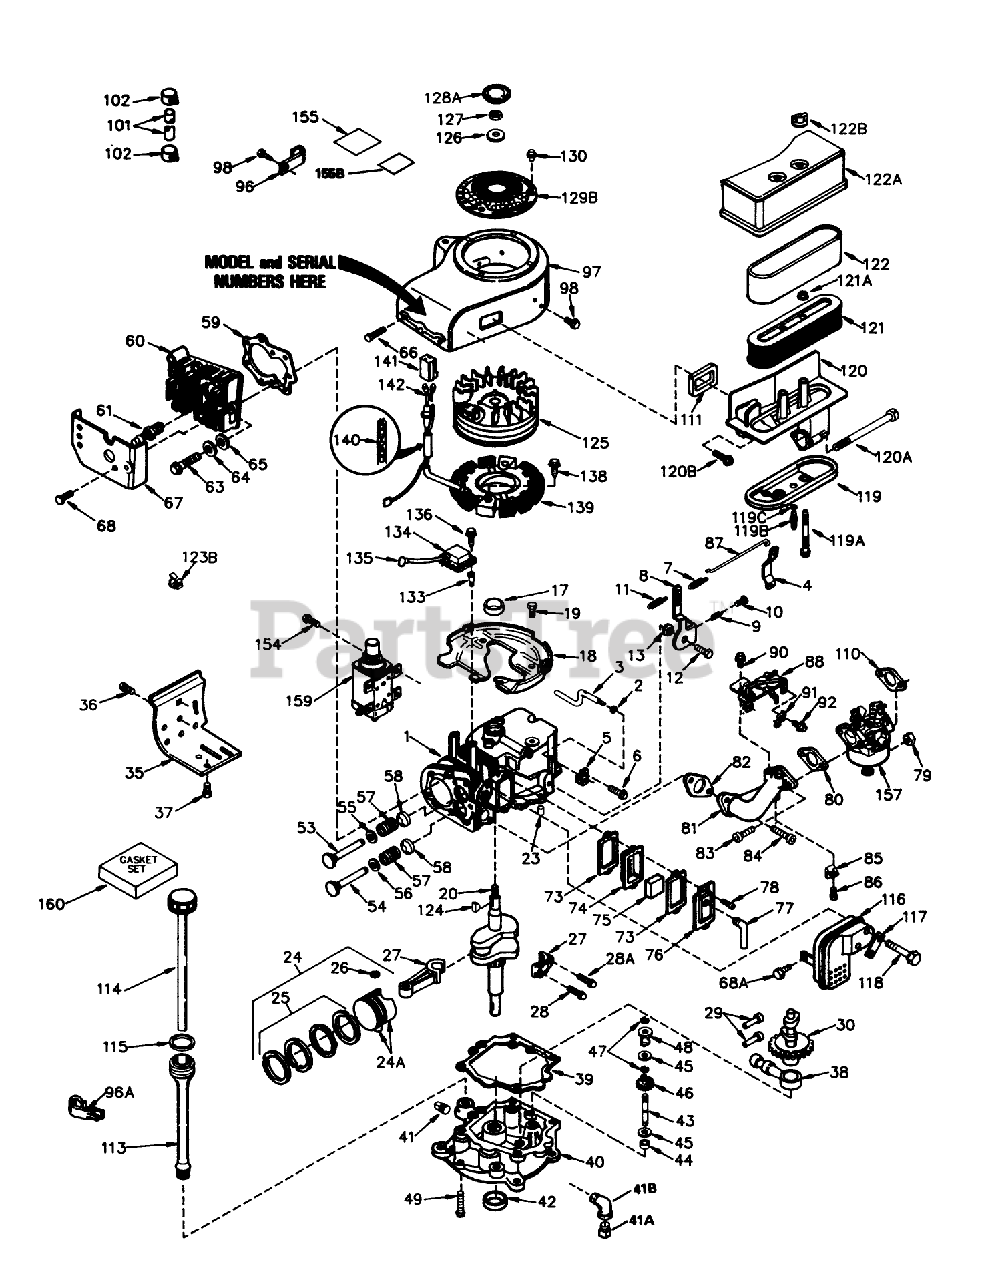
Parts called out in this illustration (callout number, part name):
1	2006A77 WIZARD ROTA
2	Washer-Flat
3	Rod, Governor
4	Governor Lever
5	Clamp-Lever, Governor
6	Screw
7	Spring, Extension
8	Lever, Control (Incl. Ref. #11, 12, 13 110)
9	61709/GIL1515A/95-5
10	Screw
11	Spring, Control
12	SCREW, HEX WASHER HD.
13	Bell crank
17	Seal-Oil
18	Baffle-Blower Housing
19	Screw (1/4-20x19/32)
20	Crankshaft
23	Pin-Dowel
24	Piston, Pin Ring Assy.(Std.) (Incl. Ref. #24A, 25 26)
24	Piston, Pin Ring Assy. (.010 oversize) (Incl. Ref. #24A, 25 26)
24	Piston, Pin Ring Assy. (.020 oversize) (Incl. Ref. #24A, 25 26)
24A	Piston Pin Assy. (Std.) (Incl. Ref. #26)
24A	Piston Pin Assy. (.010 oversize) (Incl. Ref. #26)
24A	Piston Pin Assy. (.020 oversize) (Incl. Ref. #26)
25	Ring Set (Std.)
25	Ring Set (.010" OS)
25	Ring Set (.020" OS)
27	Rod Assy., Connecting (Incl. Ref. #28 28A)
28	Bolt-Rod
28A	Bolt-Rod
29	Lifter-Valve
30	Camshaft (Mechanical Compression Release)
35	Extension-Housing, Blower
36	Screw
37	Screw
38	Pump, Oil
39	Cylinder Cover Gasket
40	Flange Assy., Mounting (Incl. Ref.#41, 41A, 42, 43 45)
41	Plug, Drain
41A	Plug, Oil drain
41B	Elbow, 90 Degrees (Can be purchased locally)
42	Seal-Oil
43	Shaft, Governor
44	Spacer Assy. Governor (Incl. Ref. #41)
45	Washer
46	Gear Assy., Governor (Incl. Ref. #45)
47	Ring-Retaining
48	Spool-Governor
49	Screw (1/4-20x1-3/16)
53	Valve, Exhaust (Standard)(Incl. No. 9)
53	Valve, Exhaust (1/32" oversize)(Incl. No. 9)
54	Valve, Intake (Std.) (Incl. Ref. #58)
54	Valve, Intake (1/32" oversize) (Incl. Ref. #58)
55	Cap-Spring, Valve
56	Seal-Intake Valve
57	Spring-Valve
58	Keeper-Spring, Valve
59	Gasket-Cylinder Head
60	Head Cylinder
61	Plug, Spark (Champion RCJ-8)
63	Screw (5/16-18 X 2)
64	Washer-Belleville
65	Washer-Flat
66	Screw (5/16-18x3/4)
67	Cover-Cylinder Head
68	Screw (1/4-20 X 5/8)
68A	Screw (1/2-20x5/8)
73	Gasket-Cover, Valve
74	Body-Breather
75	Element-Breather
76	Cover-Valve
77	Tube-Breather
78	Screw
79	Nut and Lock Washer (1/4-28)
80	Gasket-Carburetor To Intake Pipe
81	Pipe, Intake
82	Gasket-Pipe, Intake
83	Screw (1/4-28x1)
84	Screw (T-30, 5/16-18x1-3/32)
85	Bracket, Intake Pipe
86	Screw (1/4-20 X 5/8)
87	Link, Throttle
88	Bracket Assy., Control
90	Screw (10-24 x 9/16)
91	Conduit
92	Screw (10-32 x 3/8)
96	Clip Oil Tube
96A	Clip, Oil fill tube
97	Housing, Blower
98	Screw
101	Line-Fuel
102	Clamp-Line, Fuel
110	Clutch Arm Assembly
111	Gasket, Blower Housing
113	Tube-Fill, Oil
114	Dipstick, Oil
115	O-Ring
116	Muffler Assy.
117	62513 SNWTHWR W/284
118	Screw, Hex Hd.
119	Plate, Support
119A	Screw, Truss Hd.
119B	Fitting, Breather Tube
119C	0 Ring
120	Body, Air Cleaner
120A	Screw, Fil. Hd.
120B	Screw, Hex Washer Hd. Self-drill, Self-tap
121	Element, Air Cleaner (Incl. Ref. #121A)
121A	Nut Lockwasher
122	Filter, Poly Pre-cleaner
122A	Cover, Air Cleaner
122B	Nut, Wing
123B	51004 GIL ROTARY TI
124	Key-Flywheel
125	Flywheel ASM
126	Washer-Belleville
127	Nut-Flywheel
128A	Plug, Screen
129B	Screen, Starter
130	Pop Rivet (Can be purchased locally)
134	Solid State ASM
135	Cover-Spark Plug
136	Screw
138	Screw (1/4-20 x 3/4)
139	Coil Assy., Alternator (3 Amp D.C.) (Incl. Ref. #140, 141 142)
140	Diode
141	Connector Body
142	Terminal-Female
154	Screw
155	Decal-Name
155B	Decal, Instruction
157	Carburetor (Incl. Ref. #80)
159	Pin
160	Gasket Set (Incl. items marked *)
